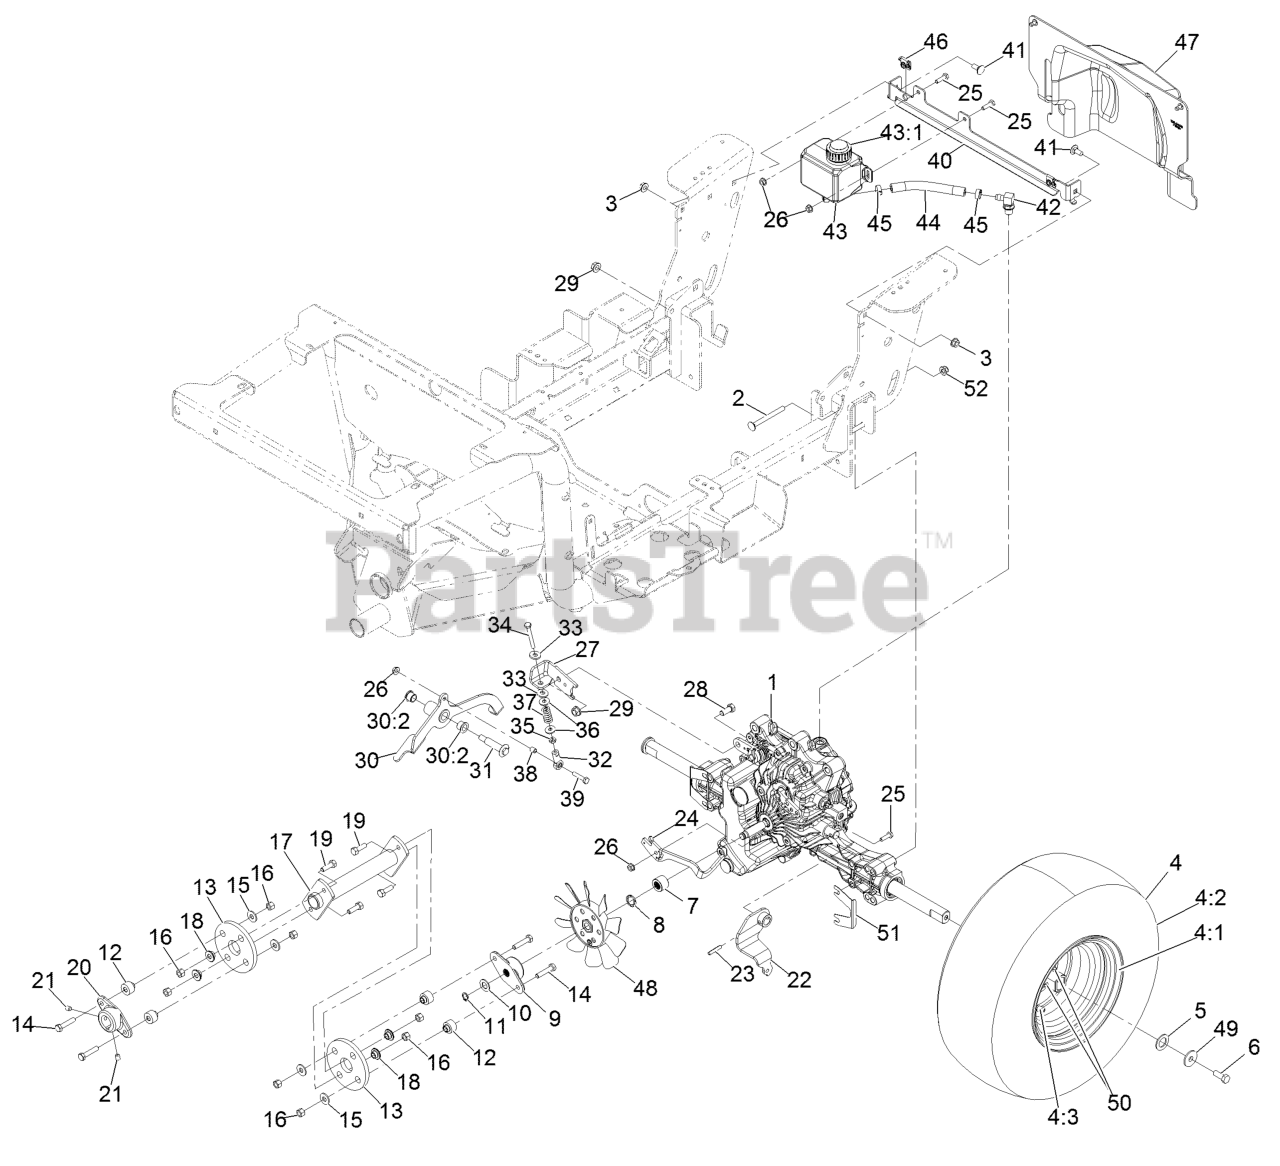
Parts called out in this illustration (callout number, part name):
1	TRANSAXLE
2	Screw-CARR
4	WHEEL AND TIRE ASM
4:3	Stem-Valve
5	WASHER-NYLON
6	SCREW-HH, LOCK
7	SPACER-SHAFT, INPUT
8	WASHER-SPRING
9	HUB-SHAFT, TRANSAXLE
10	SPACER
11	RING-RETAINING
12	SPACER-COUPLING, RUBBER
13	COUPLING-RUBBER
14	SCREW-HH
15	WASHER-FLAT
16	NUT-HEX
17	SHAFT-DRIVE
18	SPACER-COUPLER, RUBBER
19	SCREW-HH
20	HUB-SHAFT, ENGINE
21	SETSCREW
22	ARM-MOTION
23	PIN-SPIRAL
24	ARM-RELEASE
25	SCREW-HH
27	ARM-BRAKE
28	SCREW-HH
30	BRAKE LEVER ASM
30:2	BEARING-FLANGE
31	BOLT-SHOULDER
32	ROD END-BALL JOINT
33	WASHER-SPRING
34	SCREW-HH
35	NUT-JAM
36	WASHER-FLAT
37	SPRING-COMPRESSION
38	SPACER
39	SCREW-HH
40	BRACKET-MOUNT, TANK
41	SCREW-CARR
42	FITTING-90 DEG
43	TANK ASM
43:1	CAP-TANK
44	HOSE-EXPANSION
46	RECEPTACLE-CLIP, MINI
47	TRANSAXLE COVER ASM
48	FAN-7 INCH
49	SPACER-WHEEL
50	SCREW-SET, SQH
51	SPACER-TRANSAXLE
52	NUT-HF, NI
